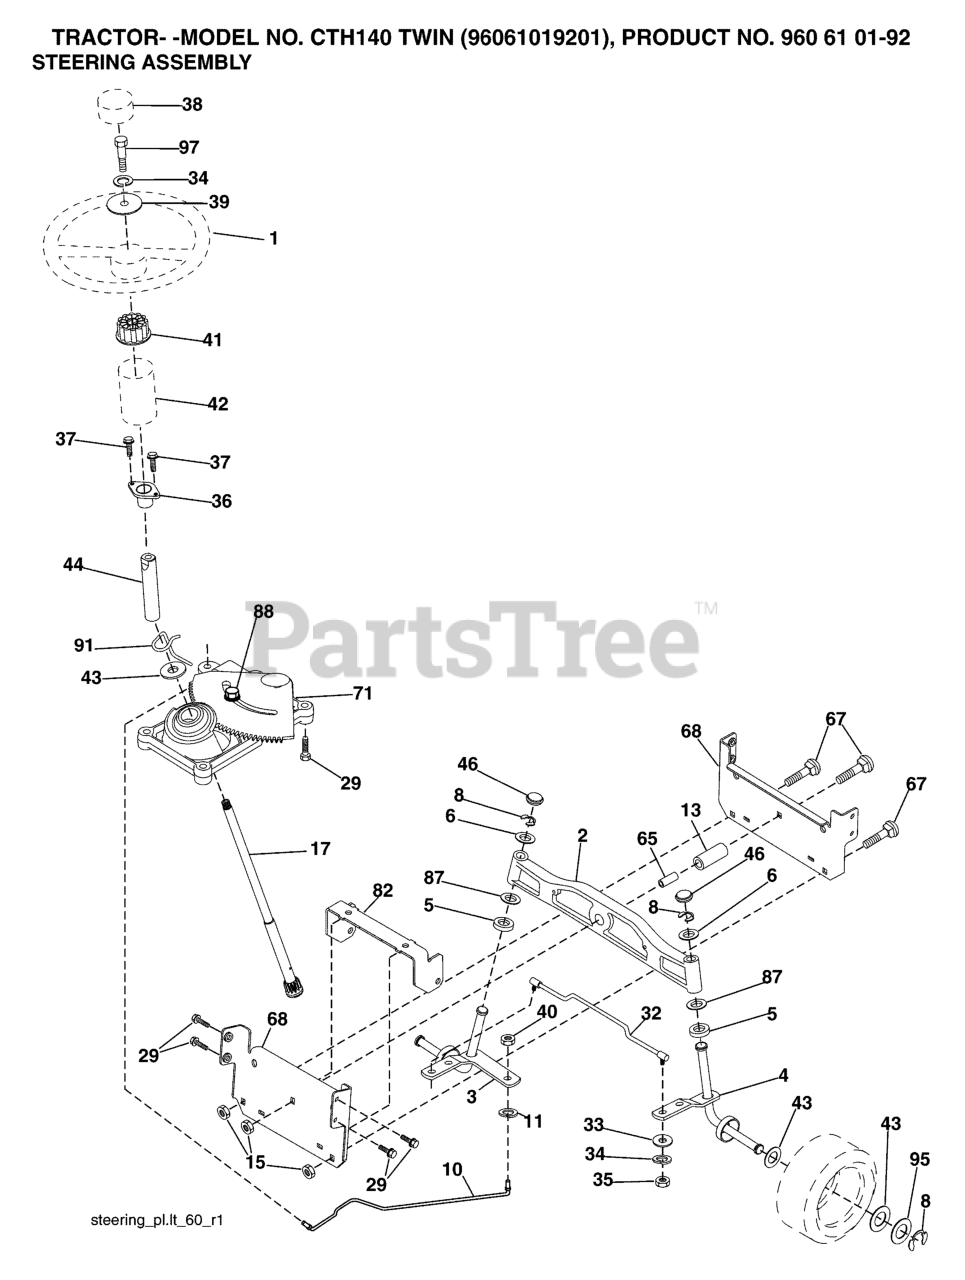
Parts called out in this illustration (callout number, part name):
1	STEERING WHEEL
2	AXLE ASSY FRONT
3	SPINDLE.ASM.LH.15"TIRES
4	SPINDLE.ASM.RH.15"TIRES
5	THRUST WASHER
10	DRAGLINK.15".TIRES.2001
11	WASHER, LOCK 3/8
13	TUBE, PIVOT AXLE
15	NUT
17	SHAFT STEERING SPLINE
29	SCREW, 3/8-16X3/4
33	WASHER M
34	WASHER.LOCK.HVY.HLCL.SPR.5/16
35	NUT, CROWNLOCK
36	BUSHING, STEERING
37	SCREW.TT.#10-32X.5.3/8.FLANGE
38	INSERT.CAP.STRG.WH.GRAY
39	WASHER.11/32
40	NUT CROWNLOCK 3/8-24
41	ADAPTER, WHEEL STNG..
42	BOOT, STEERING
44	SHAFT.EXTEN.STRG.SPLINE
46	CAP.SPINDLE.BLACK
65	SPACER BRACE AXLE
67	BOLT CARRIAGE
68	BRACE.AXLE.15"TIRES
71	STEERING ASM
82	BRACKET.SUSP.CHASSIS.FRONT.15
87	WASHER, FLAT .781 X 1 1/2"
88	BOLT, SHOULDER 7/16-20
91	CLIP.STEERING
95	WASHER.HARDENED
